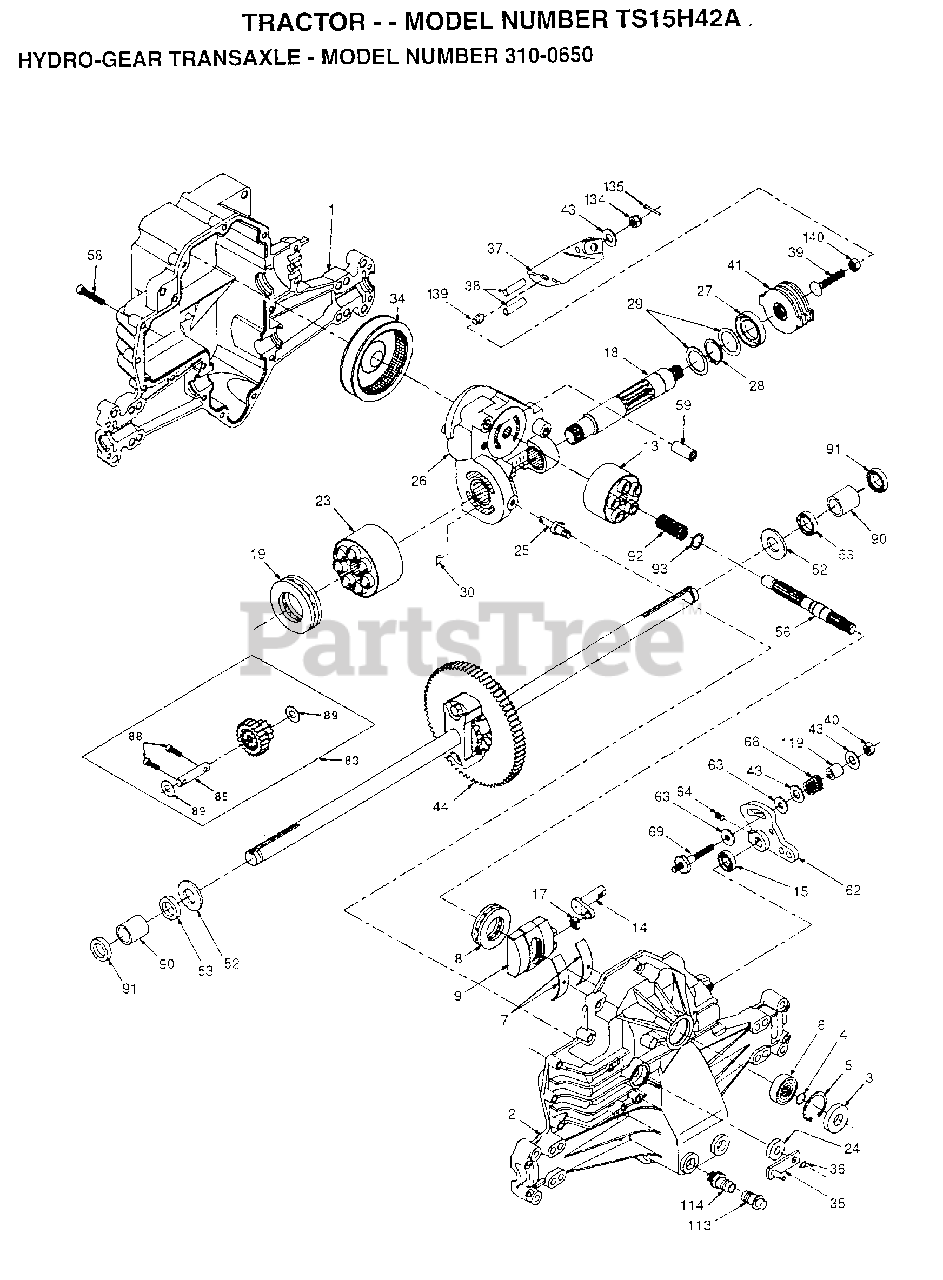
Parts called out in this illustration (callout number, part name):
1	HOUSING.L.50074RM
2	HOUSING.UP.70125
3	SEAL.9008000-0128
4	RING.RET.2003016.
5	RING.RET.2003052.
6	BEARING.(50552)42X68X16
7	CRADLE- 2003023.
8	BEARING.THU.50551
9	SWASHPLT.2003087.
13	BLOCK.CLYN.70079.
14	ARM.TRUN.2003005.
15	SEAL.9008000-0126
17	GUIDE.2000015.
18	SHAFT.MOTOR.50449
19	BEARING.THU.50552
23	BLOCK.CYLIN.70082
24	SEAL.LIP.45074
25	ACTUATOR.2003555
26	KIT.CEN.SEC.70250
27	SEAL.LIP.45075
28	RING RETAIN 50007
29	WASHER.44872
34	ELEMENT.OIL.44964
35	ARM.BYPASS.50270
36	RING.RETAIN.44870
37	ARM.ACTUAT.23710
38	PIN.ACTUAT.44891
39	BOLT.50316
40	NUT.LOCK.HX.50317
41	KIT.BRAKE.70135
43	WASHER HYD 44130
44	DIFFRENTIAL.70226
52	WASHER.HYD.44875
53	SEAL.HYDRO.45076
56	SHAFT.INPUT.50005
58	BOLT.1/4-20.44876
59	PIN.HYDRO.50002
62	ARM.CONTROL.50254
63	PUCK.DAMPER.50281
64	SCREW.SET.50018.
68	SPRING.HYD.50277
69	STUD.5/16-24.DANA
83	JACKSHAFT/PINION GEAR.70132
85	PIN.SHAFT 50559
88	SCREW.CAP.50154.
89	WASHER.HYD.50132
90	BEARING.SLV.50118
91	SEAL.WIPER.50941
92	SPRING.2003014.
93	WASHER.2003017
113	CAP.VENT.70109
114	O-RING.ASM.70110
119	SPACER.HYD.50278
134	NUT.CAS.HYD.44142
135	PIN.COT.HYD.44101
139	SPRING.COMP.50431
140	NUT.HEX.50269
